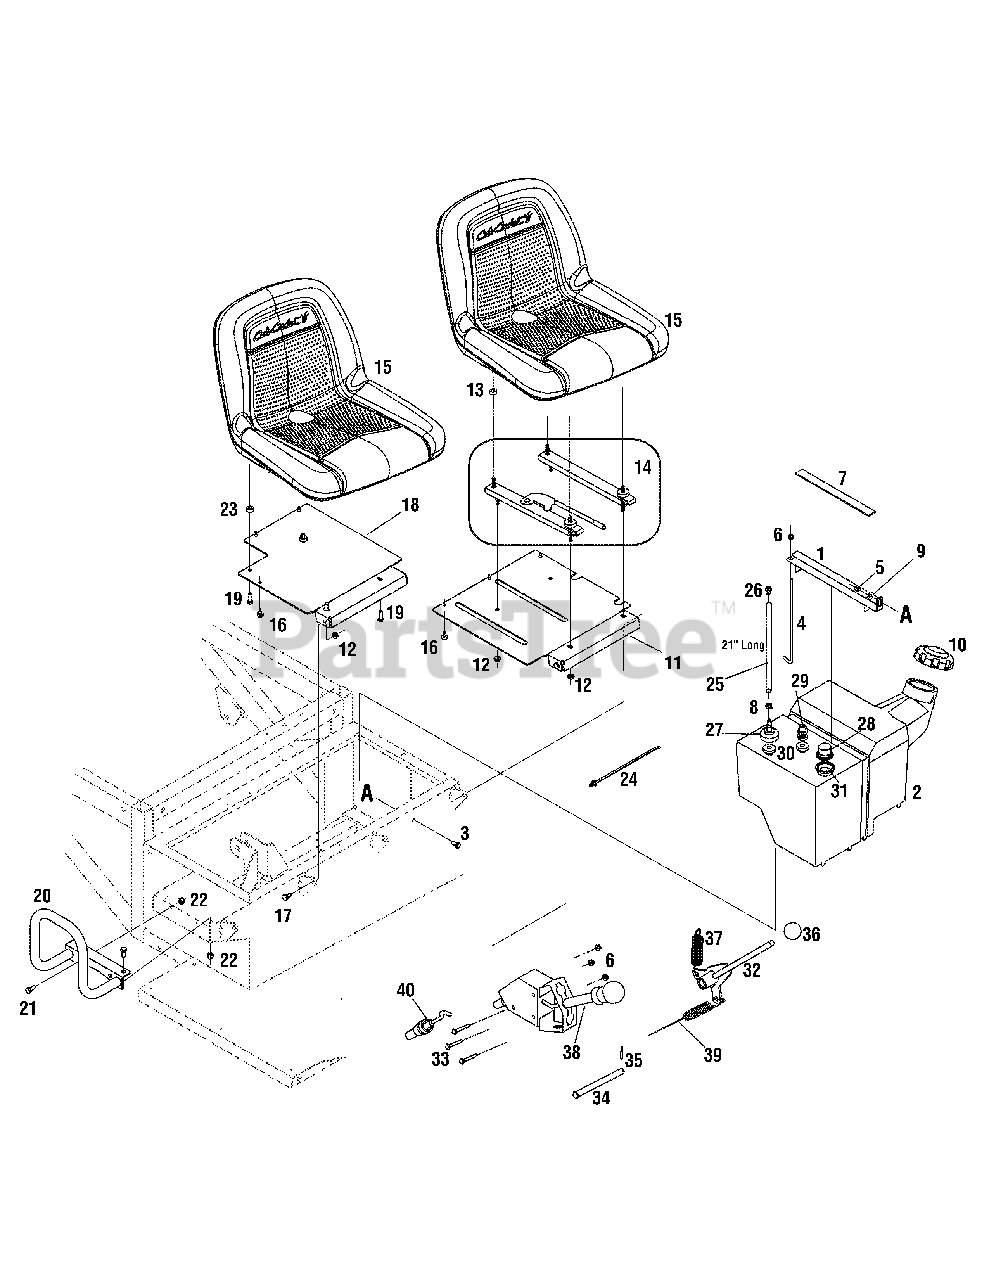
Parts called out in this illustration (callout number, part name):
1	Bracket Assembly, Fuel Tank
2	Tank Assembly, Fuel
3	Hex Screw, 5/16-18 x .75
4	Hold-down Rod, Fuel Tank
5	Sems Nut, 5/16-18
6	Nut, Flange Lock, 1/4-20
7	Gasket, Fuel Tank (11")
8	Clamp, Hose
9	Washer, .349 x .879 x .063
10	Cap, Fuel
11	Plate, Seat, LH
12	Nut, Flange Lock, 5/16-18, Gr5
13	Spacer, Seat
14	Track Assembly, Seat
17	Shoulder Screw,.435 x.178-5/16 x.56
18	Plate, Seat, RH
19	Hex Screw, 5/16-18 x 1.0
22	Nut, Hex Lock Nylon, 3/8-16
23	Spacer,.315 x.750 x.375
24	Cable Tie
25	Fuel Line Hose
27	Fuel Return Fitting
28	Fuel Tank Gauge
29	Fuel Tank Shut Off Valve
30	Grommet
32	Diff Lock Shift Assembly
33	Hex Screw, 1/4-20 x 2.25
34	Clevis Pin
35	Cotter Pin
37	Extension Spring
38	Shifter Control
39	Diff Lock Control Cable
40	Shift Panel Control Cable
